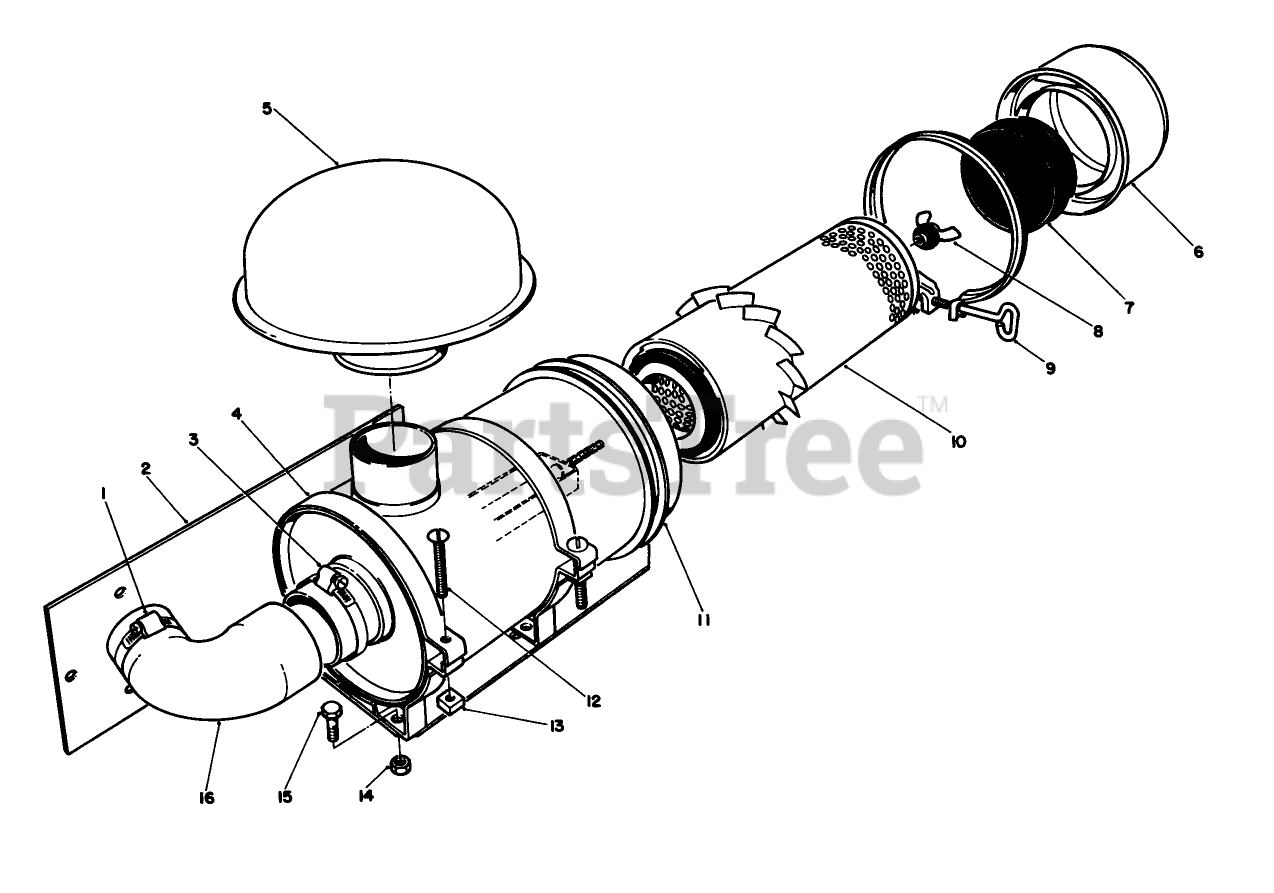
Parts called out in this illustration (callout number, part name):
1	CLAMP-HOSE
2	BRACKET-MOUNTING
3	CLAMP-HOSE
4	MOUNTING BAND ASM
5	HOOD-INLET, AIR
11	Body Assembly
12	SCREW
13	NUT-SQUARE
14	NUT-LOCK, NI
15	SCREW-HH
16	HOSE-REMOTE, AIR CLEANER
